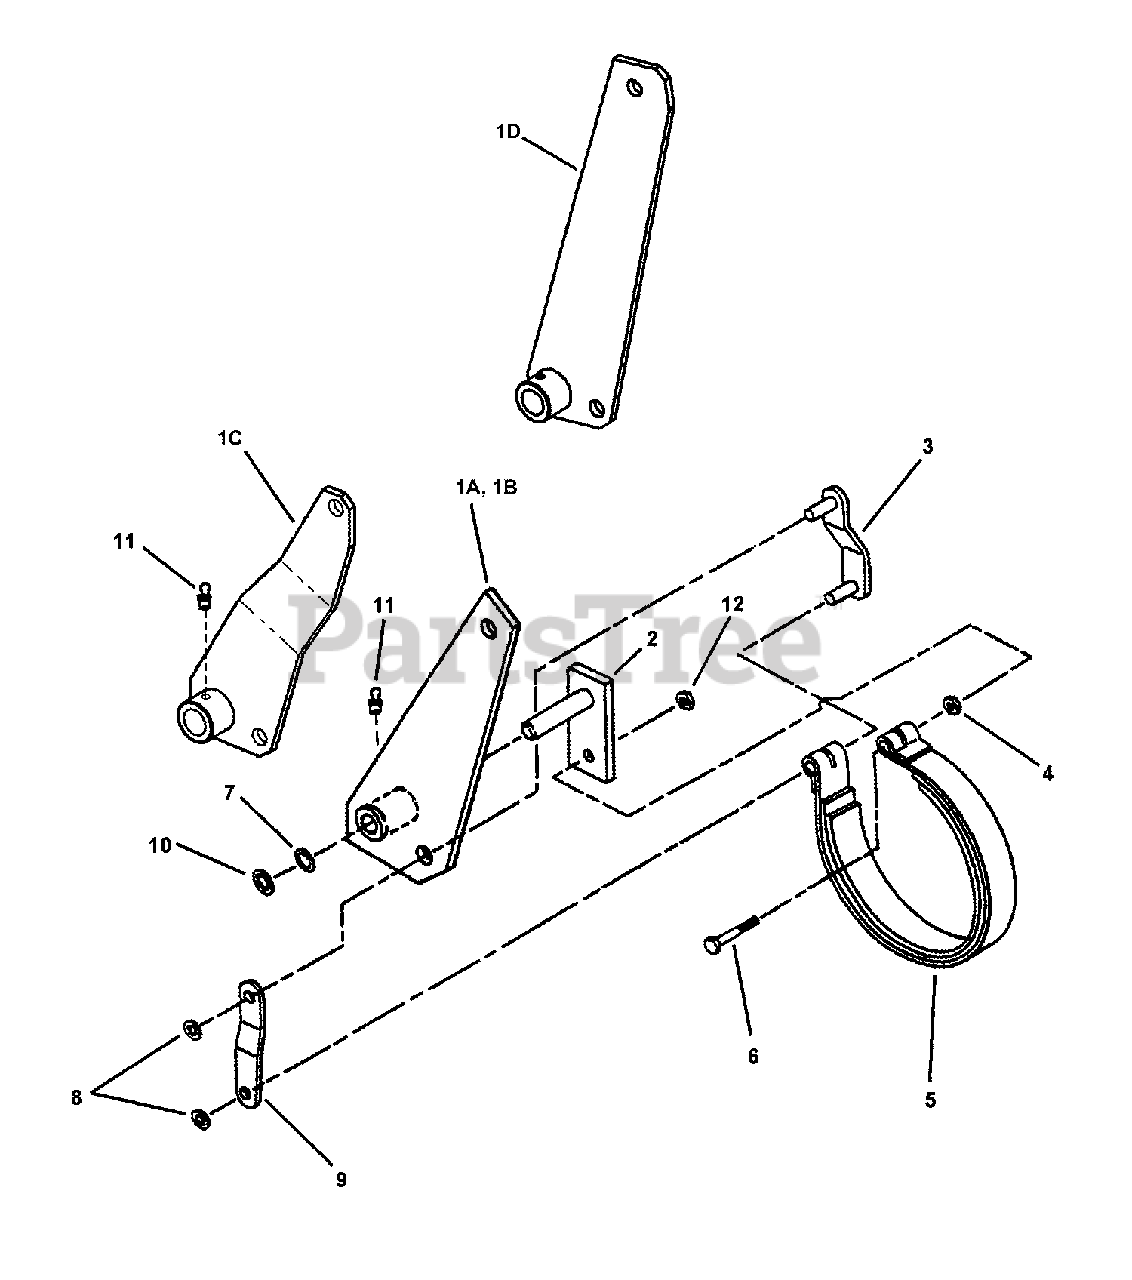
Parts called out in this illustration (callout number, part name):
1A	WELDMENT, Brake Arm, RH
1B	WELDMENT, Brake Arm, RH
1C	WELDMENT, Brake Arm, LH
1D	WELDMENT, Brake Arm, LH
2	WELDMENT, Brake Mount Stud
3	WELDMENT, Brake Link
4	NUT, 3/8-16 Hex, GR 5 or B
5	ASSEMBLY, Brake Band, 6" Thomas
6	BOLT, 3/8-16 X 2, GD5, CZ
7	BUSHING, 5/8" I.D. x 1" O.D. Machine
8	RETAINER, 3/8" Bolt
9	LINK, Brake
10	RETAINER, 5/8" Bolt
11	LUBE FITTING, 3/16 Press-In
12	NUT, 3/8-16 HEX NYLON LOCK
